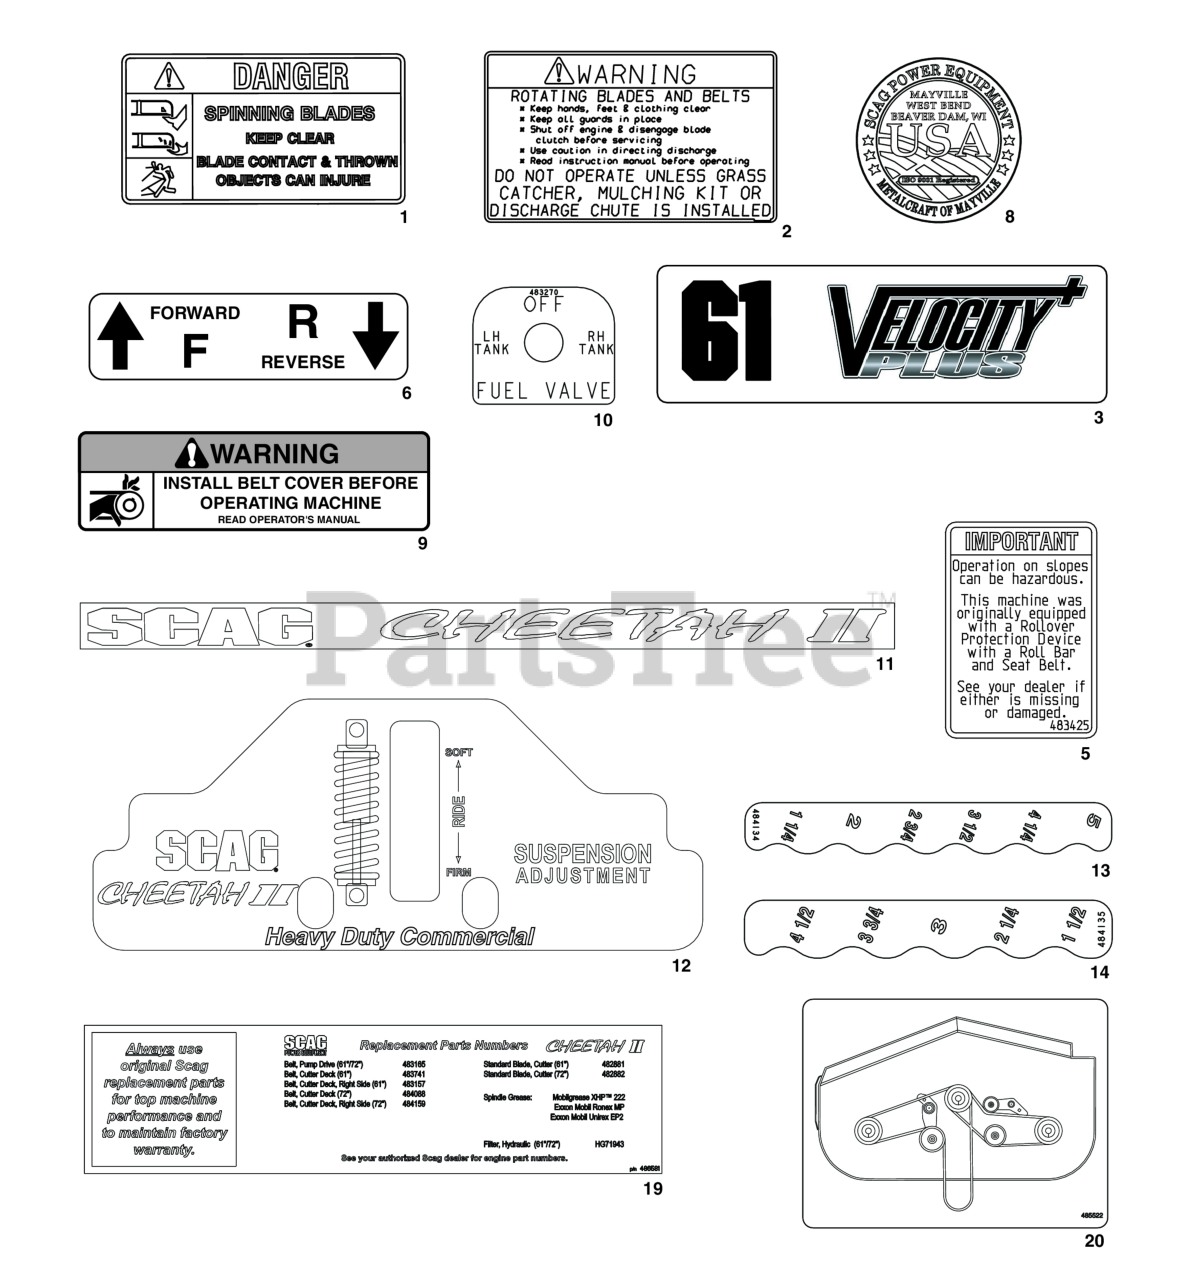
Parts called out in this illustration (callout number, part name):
1	Decal, Danger-Spinning Blades
2	Decal, Warning - Rotating Blades
3	DECAL, VELOCITY PLUS - 61
5	Decal, ROPS
6	Decal, Traction Control
8	Decal, Metalcraft - USA
9	Decal, Warning - Belt Cover
10	Decal, Fuel Shut Off
11	Decal, Scag Cheetah II
12	Decal, Suspension Adjustment
13	Decal, Deck Height - LH
14	Decal, Deck Height - RH
19	Decal, SCZII Replacement Parts
20	Decal, Belt Routing (61V)
